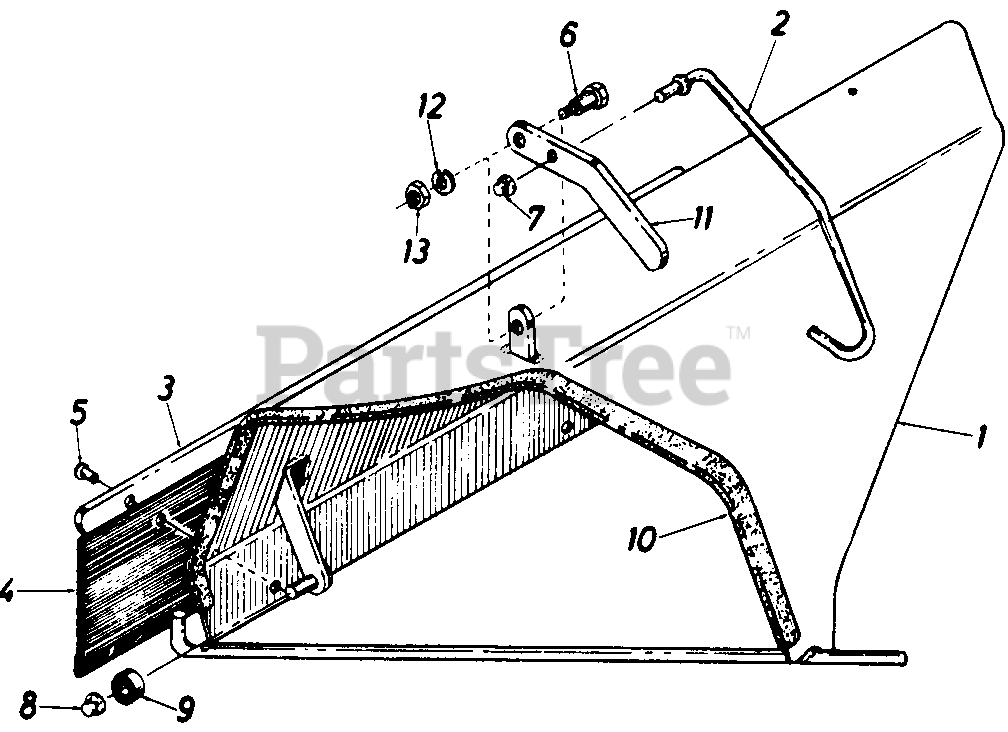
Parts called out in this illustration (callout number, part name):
1	Deflector Ass'y.
2	Hook Ass'y.
3	Retaining Strip
5	Rivet
6	Shld. Bolt 375" Dia. x.171 Lg.
7	Palnut 1/4" Rod
8	Palnut 3/8" Rod
12	L-Wash. 1/4" I.D
13	Hex Nut 1/4-20 Thd. *
